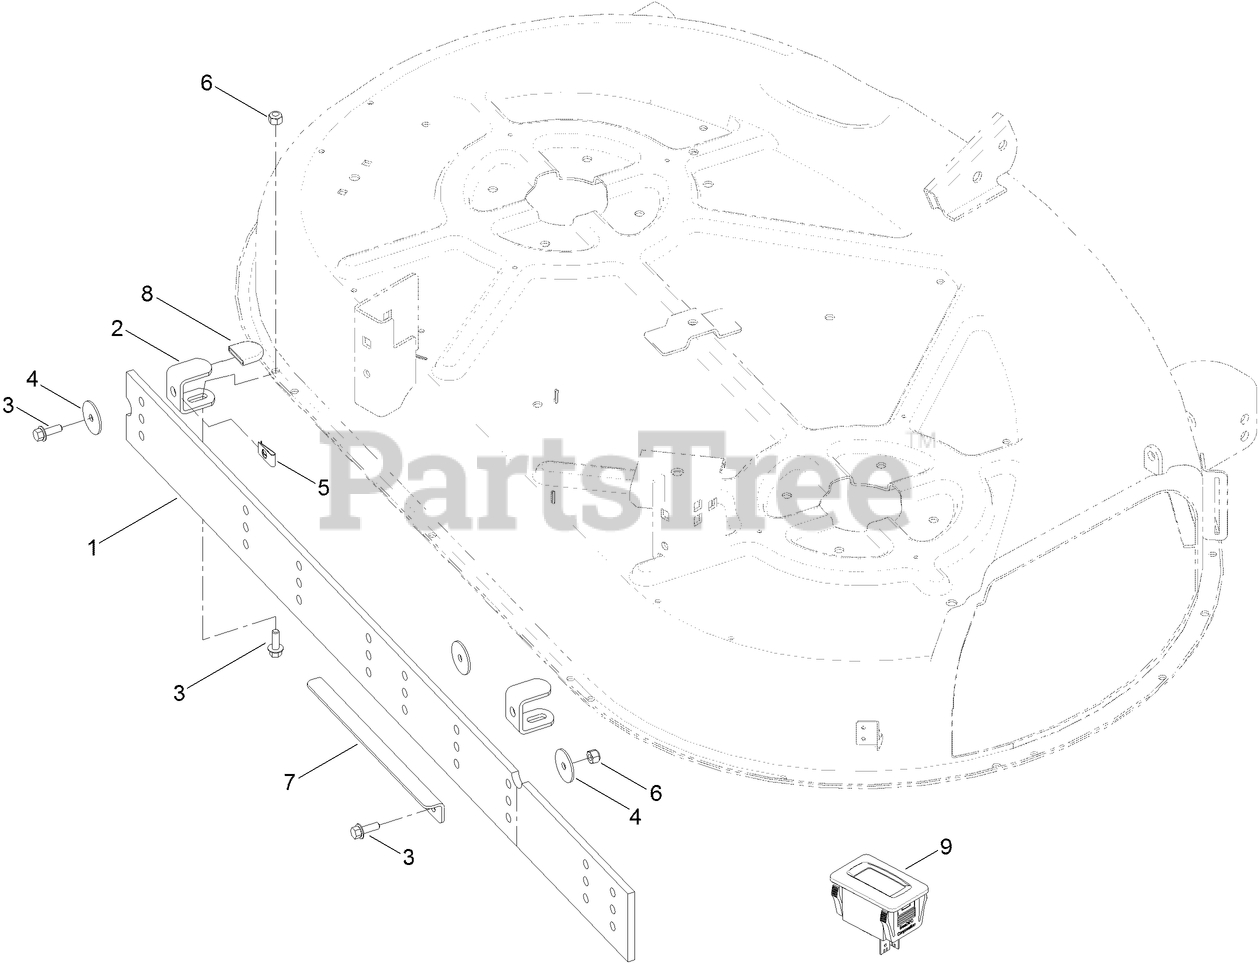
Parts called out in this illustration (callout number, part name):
2	BRACKET-MOUNTING
3	SCREW-HHF
4	WASHER-FLAT
5	NUT-SPEED
6	NUT-LOCK, NI
9	HOURMETER
